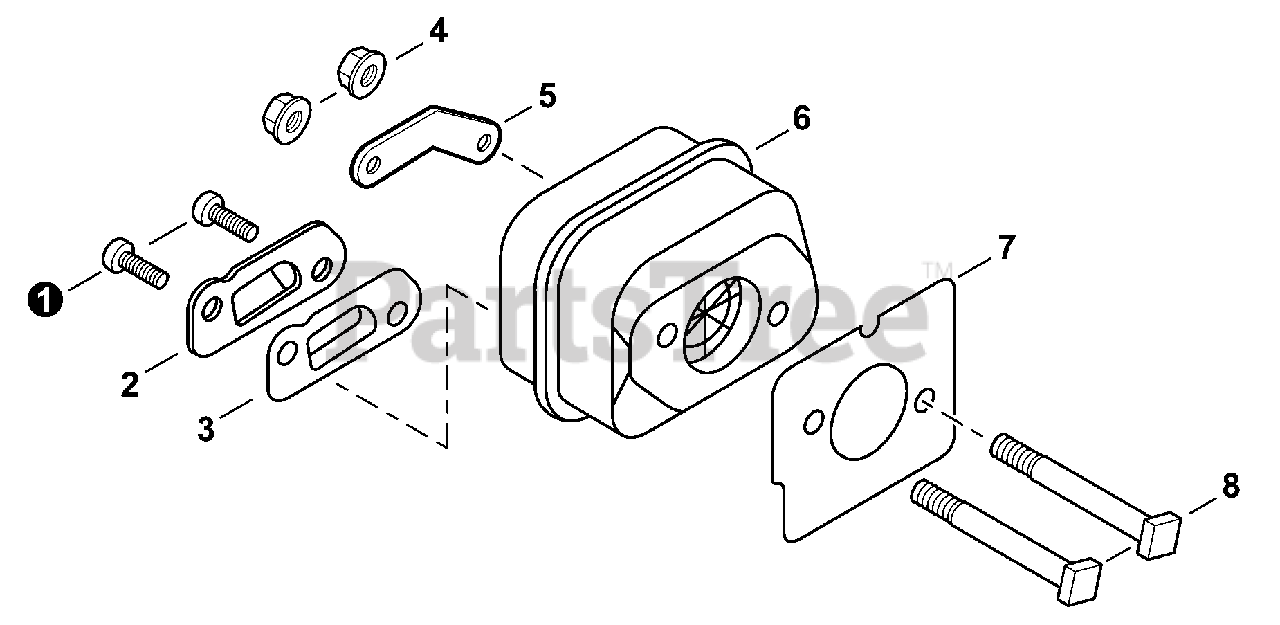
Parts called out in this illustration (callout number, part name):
1	SCREW 4×8
2	GUIDE, EXHAUST
3	SCREEN, SPARK ARRESTER
4	NUT, FLANGE M5
5	PLATE, EYE
6	MUFFLER
7	GASKET, EXHAUST
8	BOLT 5×62
